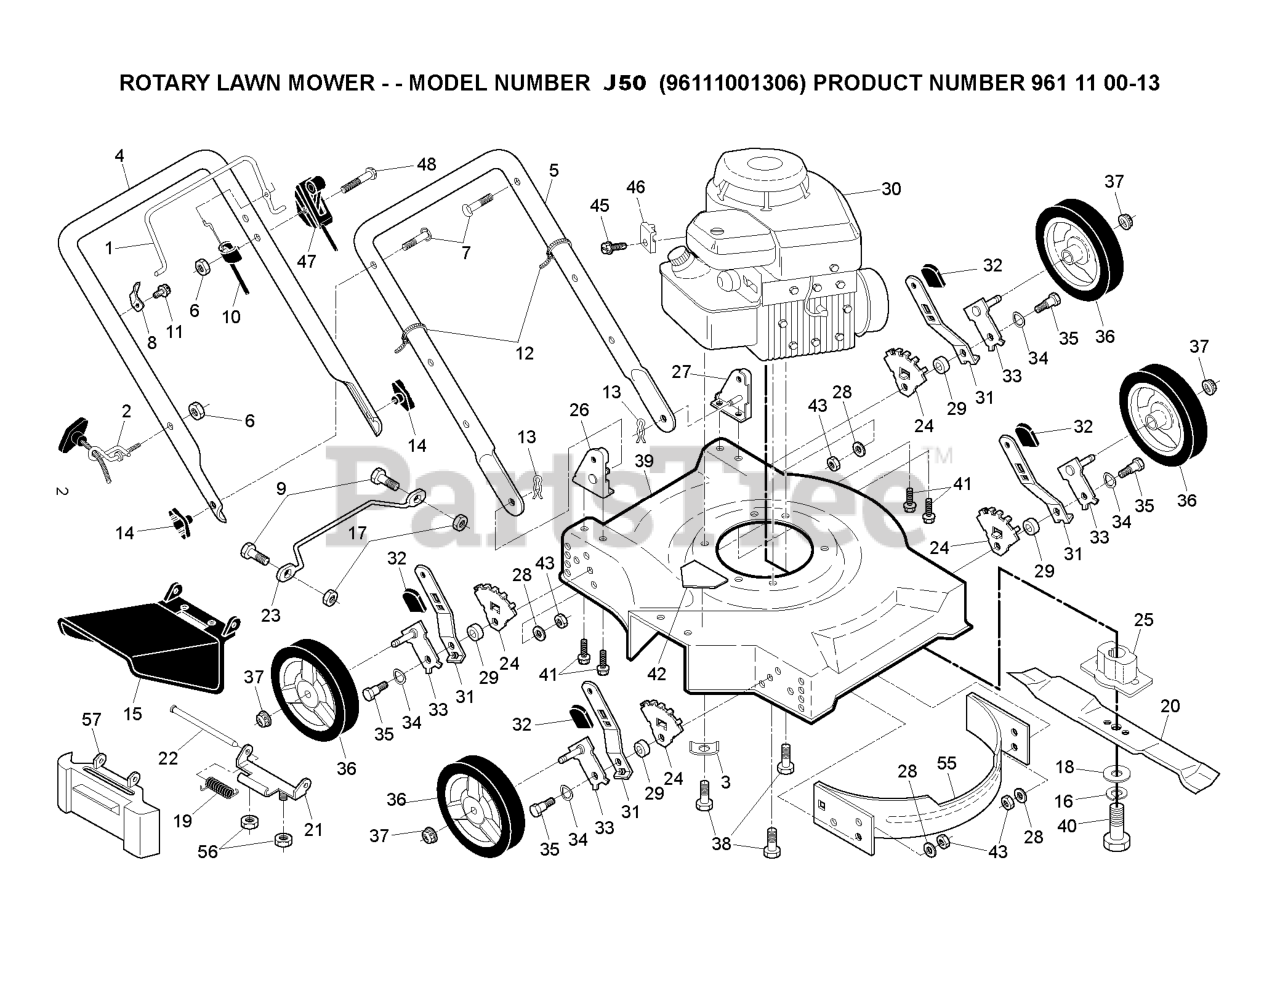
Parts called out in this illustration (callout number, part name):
1	BAIL.CONT.D.STRAIGHT.PUSH.BLK
2	RB GUIDE.ROPE.STD.BLK.ZIN WSL
3	WASHER.ENGINE.BZP
5	HANDLE
6	NUT
7	BOLT, HANDLE 5/16-18X1.75
8	BRACKET.UPSTOP.RT
9	REPL BY 817 02 10-08
10	CABLE, CONT ENG
12	TIE GUIDE
13	HAIRPIN COTTER
14	KNOB, DEFLECTOR
15	GUARD.DISCHARGE.ECON.BLK.US/CE
16	LOCKWASHER
18	WASHER,HARDEN
19	SPRING.SIDE.DISCHARGE
20	BLADE.20.MULCH.(50DK,6020MD)
21	HINGE DEFLECTOR
24	WHEEL ADJ BRACKET FRONT
25	BLADE ADAPTOR
26	HANDLE BRACKET ASM. RH
27	HANDLE BRACKET ASM. LH
28	WASHER
29	SPACER.HEIGHT.ADJUSTER
31	SELECTOR SPRING, FRONT
33	AXLE ARM ASSY.
34	WASHER.CURVED.CYLINDRICAL
35	SHOULDER BOLT 5/16-18
36	WHEEL AND TIRE ASSY, REAR
37	NUT.HEX.FLANGE.3/8-16.LO(3 2)
38	BOLT 3/8-16X1-1/8
40	SCREW, HEX HD 3/8-24 X 1-3/8
41	SCREW.5/16-18X3/4
42	DECAL.INTERNATIONL.CUTFINGER
43	NUT.CENTERLOCK.5/16-
45	SCREW.HEX.HEAD.WASHER.10-16
46	CABLE CLAMP(ENGINE)
55	FRONT BAFFLE
56	LOCKNUT.NYLOC.1/4-20
57	PLATE.MULCHER.20.ECONOMY.BLK.
